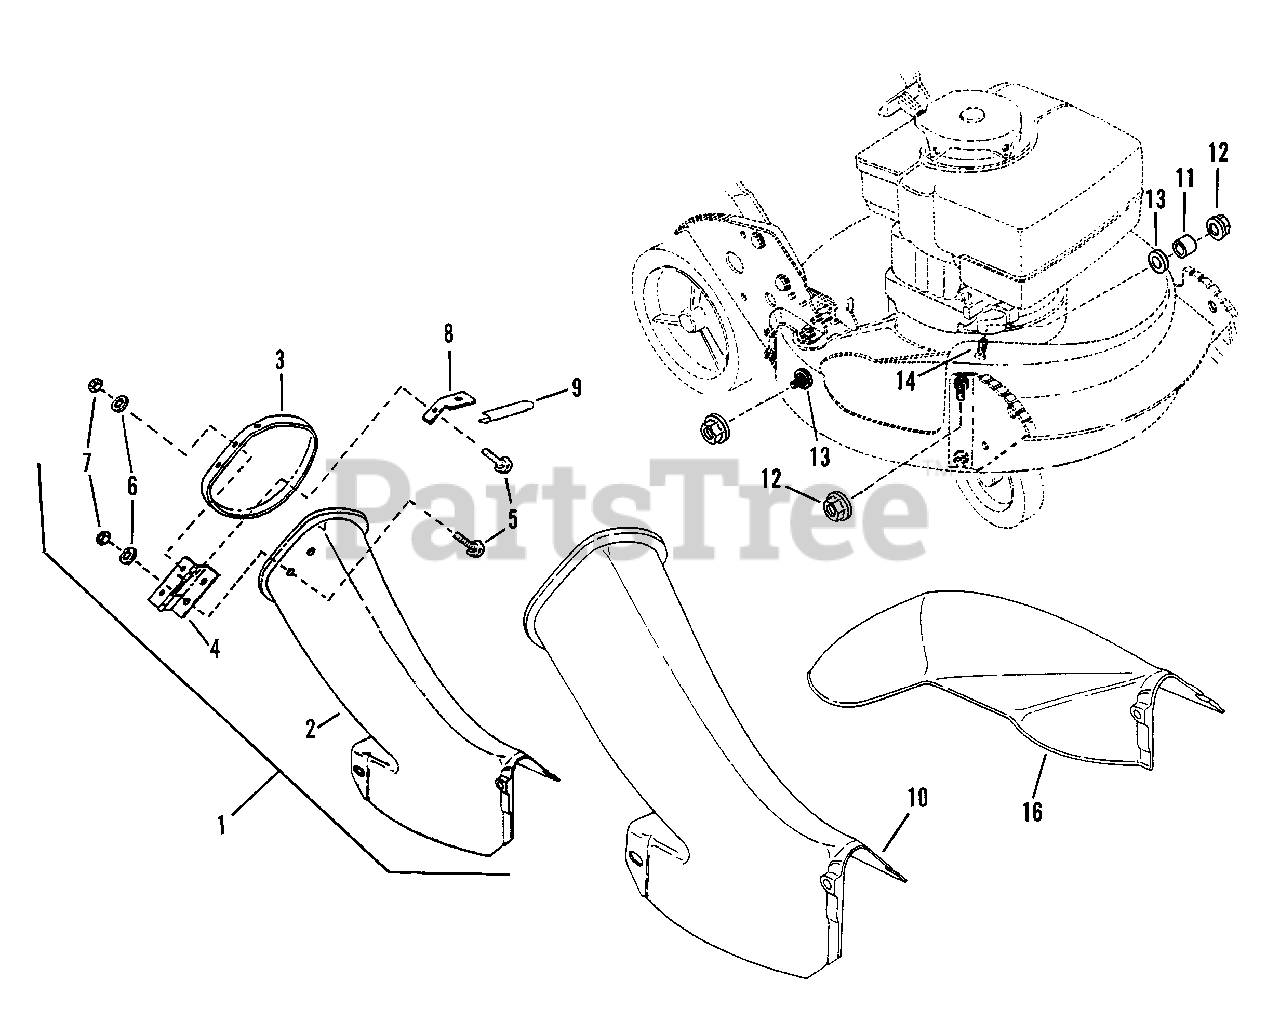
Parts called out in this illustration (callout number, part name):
1	ASSEMBLY, Bag Adapter & Cover (European Models Only)
2	ADAPTER, Grass Bag
3	COVER, Bag Adapter
4	HINGE, Chute Cover
5	BOLT, 1/4-20 x 1/2" Short Neck Carriage
6	WASHER, 1/4 Internal Tooth Lock
7	NUT, 1/4-20 Hex
8	STOP, Cover
9	MOLDING, Trim
10	ADAPTER, Grass Bag
11	SPACER
12	NUT, 5/16-18 Hex Flange
13	RETAINER, 5/16 Bolt
14	BOLT, 5/16-18 x 3/4 Short Neck Carriage
16	CHUTE, Side
